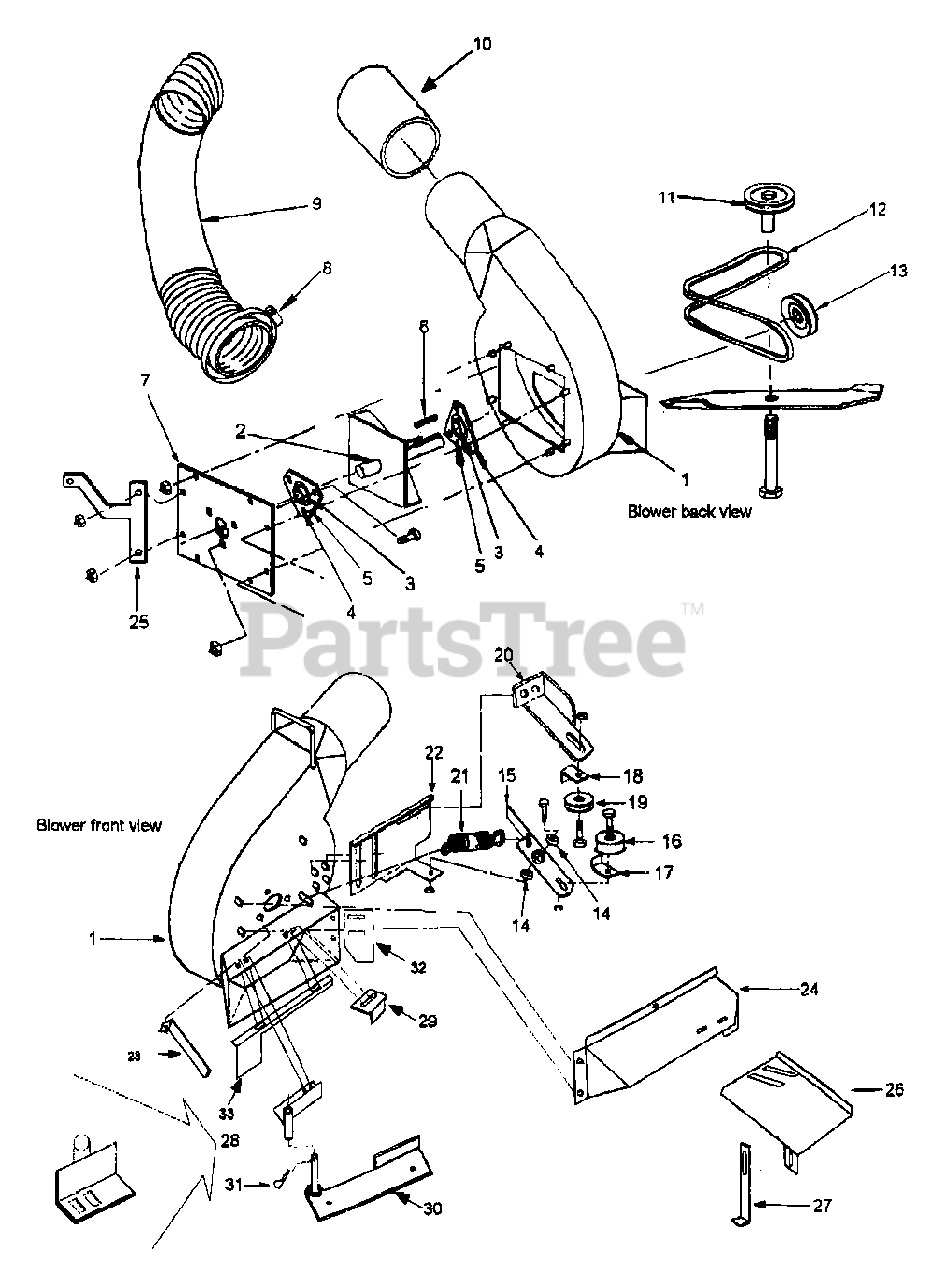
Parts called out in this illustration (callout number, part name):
1	Blower Canister
3	Fan Bearing w/ collar
4	Bearing Flangette w/ grease zerk
5	Bearing Flangette
6	Key 1/4" x 1"
7	Blower Cover Plate
8	6" Hose Clamp
9	6" x 43" Hose
10	6" Hose Insert
11	Deck Pulley
13	Blower Drive Pulley 3.5"
14	Idler Arm Bearing
15	Idler Arm
16	Flat Idler Pulley 3.25"
17	Flat Idler Pulley Bracket
18	V-Idler Pulley Bracket
19	V-Idler Pulley 3.5"
20	V Pulley Bracket
21	Idler Spring
22	Blower Pulley Bracket
23	Fan Pulley Belt Bracket
24	Blower Belt Cover
25	Pulley Bracket Support
26	Belt Guard Leg
27	Belt Guard Leg
28	Blower Mount Front
29	Blower Support Bracket
30	Blower Mount Deck
32	Blower Tab
33	Blower Blocking Plate
